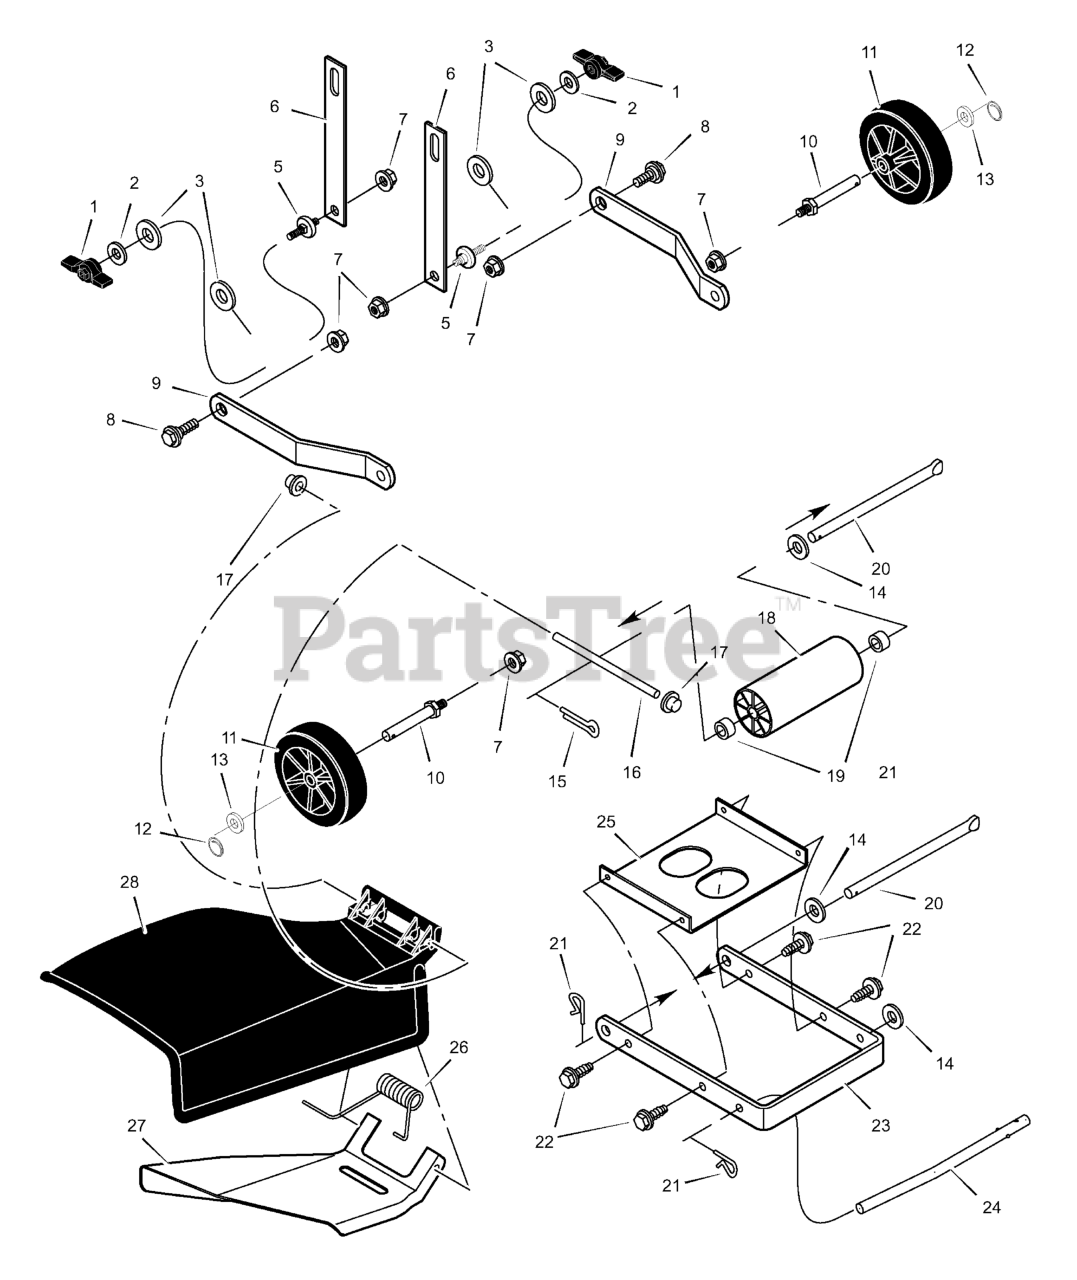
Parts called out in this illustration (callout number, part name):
1	Knob
3	Pad, Friction
5	Pin, Hanger
6	Link, Lift
7	Nut, Flange
8	Bolt, Shoulder
9	Bracket, Rear Suspension
10	BOLT, Gauge Wheel
12	Pin, Hair
15	Pin, Cotter
16	Rod, Deflector
17	Push-On Cap
20	Rod, Deck Suspension
21	Pin, Hair
23	Bracket, Front Suspension
24	Rod, Hanger
25	Stiffener
27	Deflector, Inside
28	Deflector, Chute
